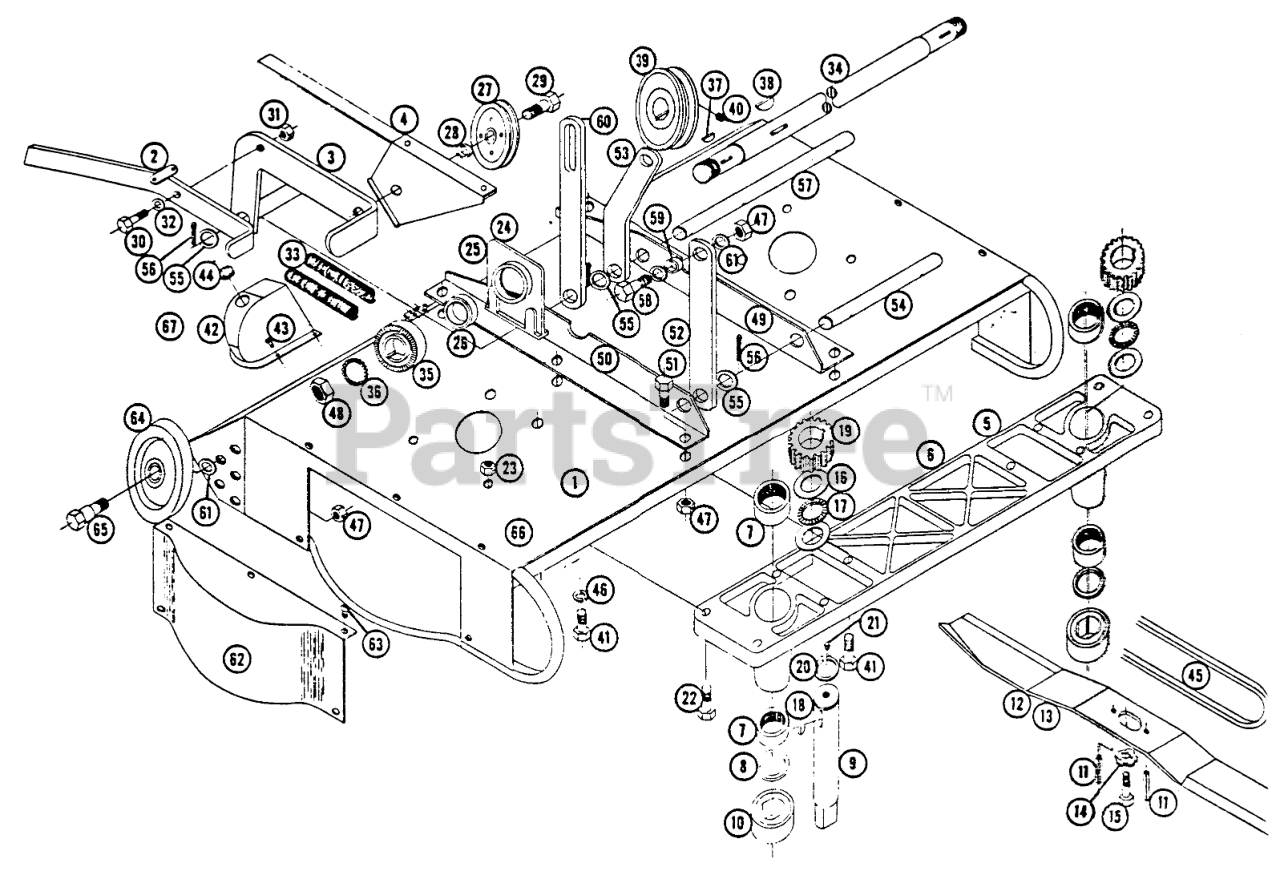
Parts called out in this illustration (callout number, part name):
1	Deck
3	59027 1969 OPC
11	Pin-Roll 1/4 x 3/4
15	Screw - Nylock 3/8-16 x 7/8
16	WASHER-THRUST
22	TEMPLATE FOR ATTCH.
23	5/16-18 Hex Nylock Nut
25	BEARING SUPPORT
30	Bolt 1/4-20 x 1 CP
31	1/4-20 Lock Nut
32	1/4 Washer
36	Washer-Lock 5/8
40	Snap Ring
41	Collar w/Setscrew
43	SCREW
44	PLUG BUTTON
46	Lockwasher 3/8
47	Nut
48	Nut 5/8 x 18
49	Bracket-L.H.
50	Bracket-R.H.
51	Bolts 3/8-16 x 3/4
52	Link-Front
55	S.A.E. Washer
56	Cotter Key
58	Bolt 3/8-16 x 1
60	Bar-Lift
61	3/8 Washer
62	Cover-End Plate
65	Bolt-Shoulder
67	Decal
